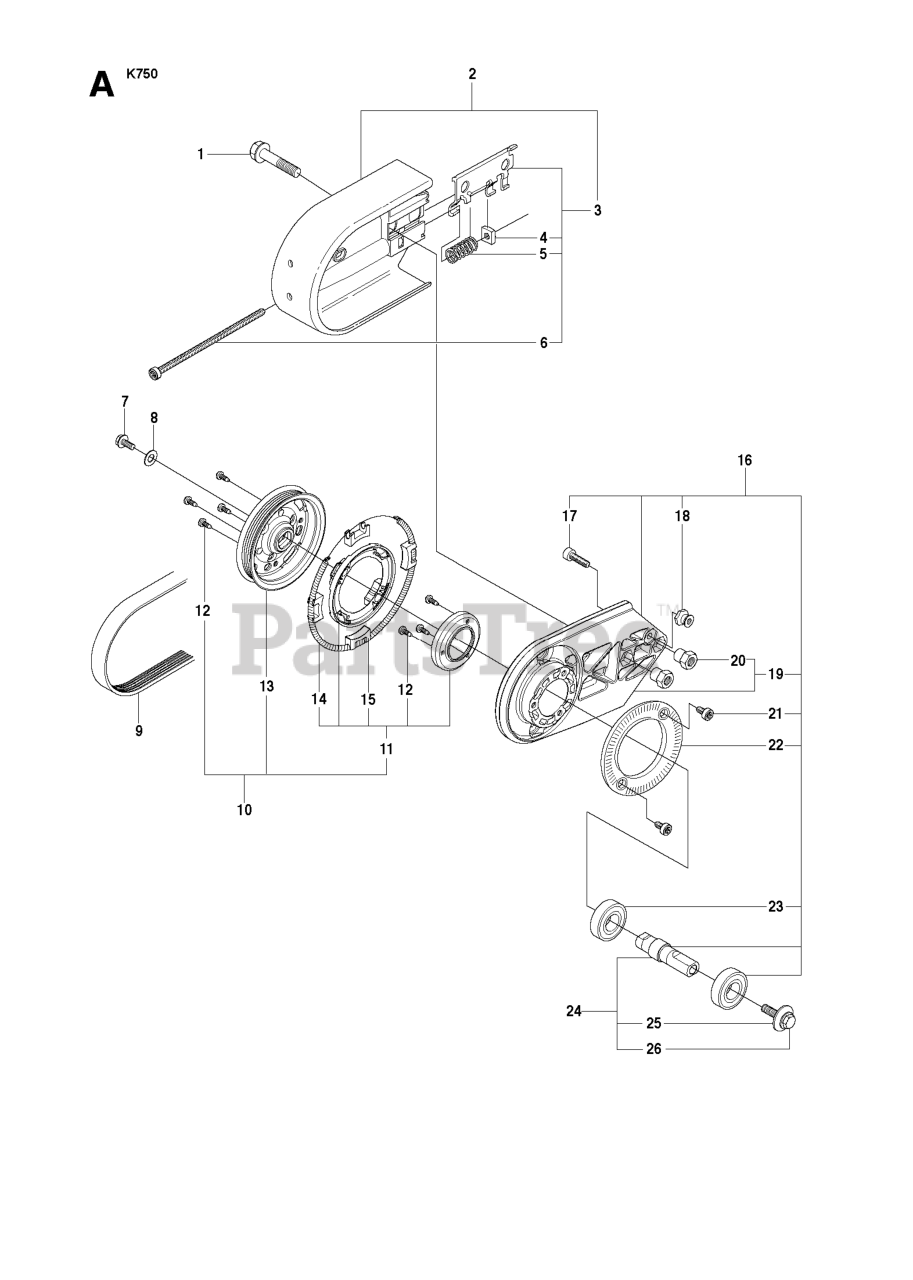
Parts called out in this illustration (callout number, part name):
2	BELT GUARD
10	PULLEY
11	CASSETTE, FRICTION RETARDER
13	PULLEY
14	DRAW SPRING
15	BRAKE SHOE
16	BEARING HOUSING
17	SCREW ITXSCM
19	HOUSING
23	BALL BEARING
25	WASHER
